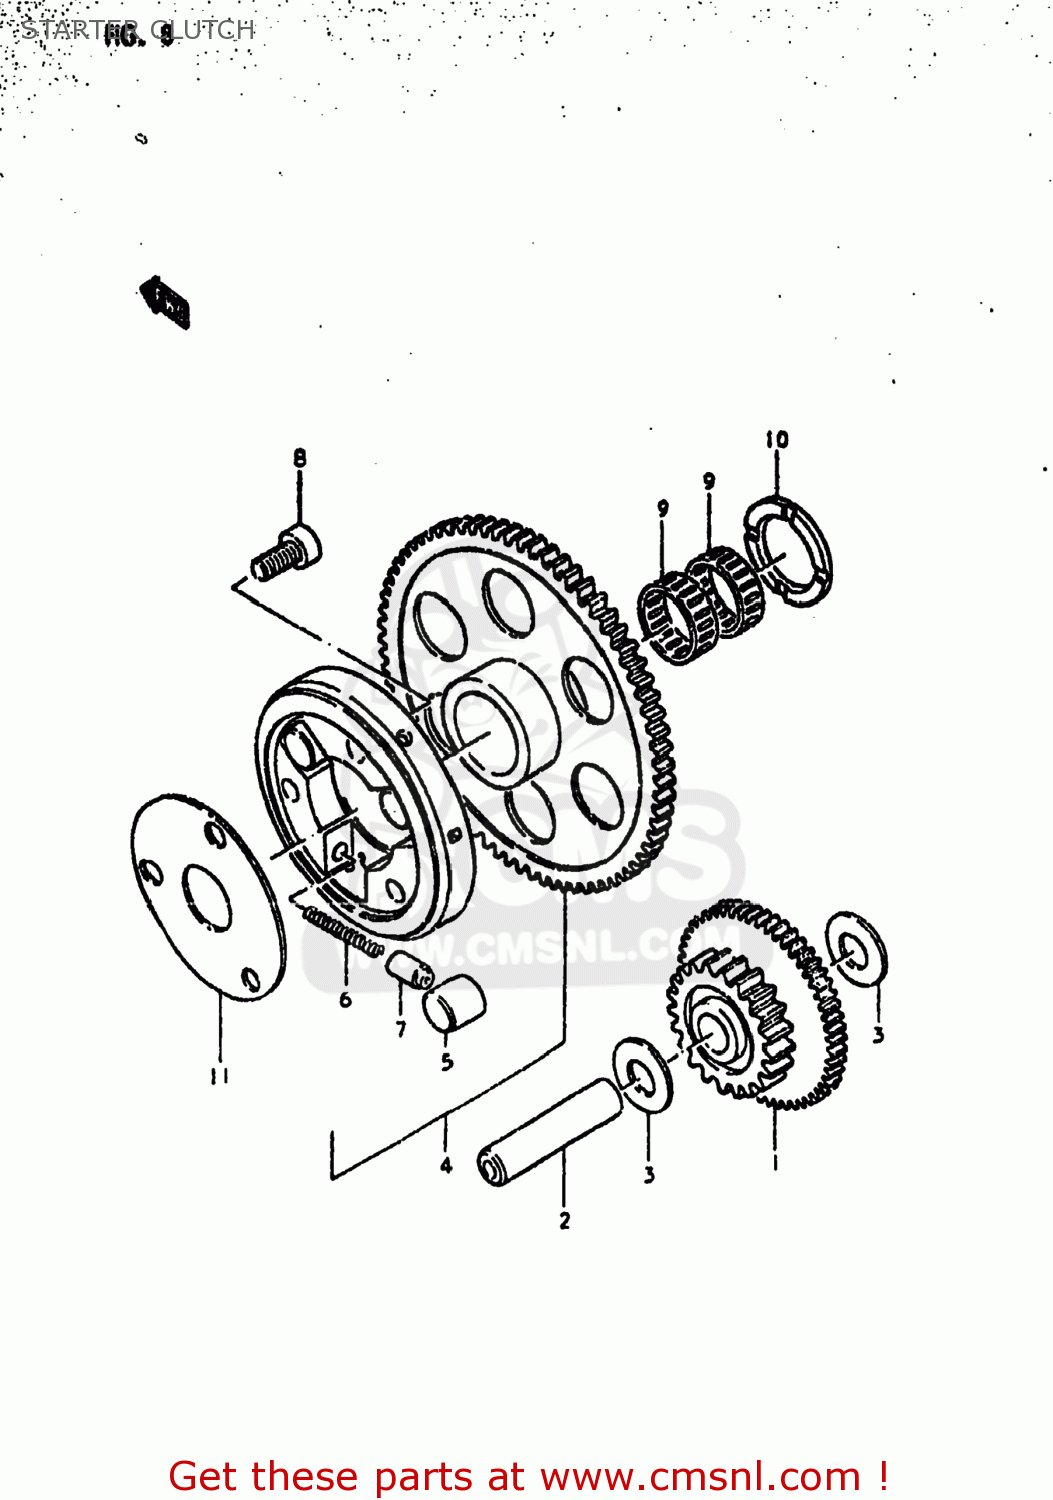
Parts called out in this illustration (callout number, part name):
1	GEAR,STARTER IDLE
2	PIN(7.4X13X56)
3	WASHER(13.3X25X0.85)
4	CLUTCH SET,STARTER
5	ROLLER(15X13)
6	SPRING
7	PIECE,PUSH
8	BOLT
9	BEARING
10	WASHER(25X38X2.5)
11	SHIM,STARTER CLUTCH HUB
